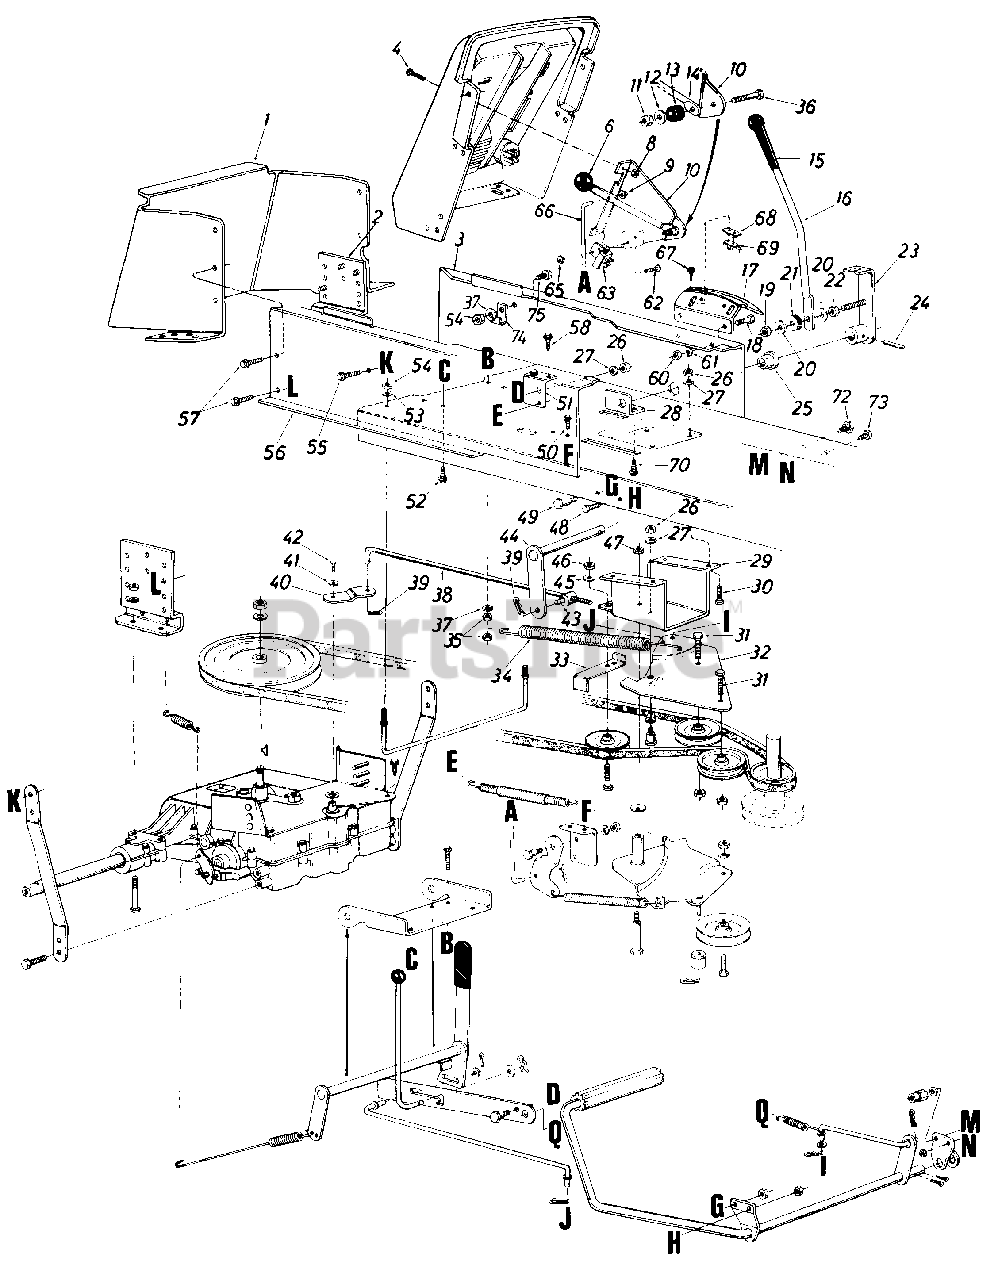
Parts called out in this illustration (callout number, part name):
3	Side Panel Upper Frame L.H.
4	Truss. Mach. Scr. 1/4-20 x .50" Lg.
6	Ball Knob
8	Hex Sems Nut 1/4-20 Thd
9	Push Cap 1/4" Rod
10	Deck Clutch Control Brkt.
11	Hex Cent. L-Nut 1/4-20 Thd.
12	Fl-Wash. .281" I.D. x .734" O.D. x .063 Thk.
13	Rubber Wash. .330" I.D. x .87" O.D. x .32 Thk.
14	Blade Clutch Lever
16	Shift Lever
19	Hex Cent. L-Nut 5/16-18 Thd.
20	Fl-Wash. .344" I.D. x .875" O.D. x .063 Thk.
21	Rubber Wash. .330" I.D. x .87" O.D. x .32 Thk.
22	Hex Nut 5/16-18 Thd.
23	Handle Mount Brkt. Ass'y.
24	Spring Pin Spiral 1/4" Dia. x 1.5" Lg.
25	Plastic Hex Bearing .625" I.D.
26	Hex Nut 5/16-18 Thd.
27	L-Wash. 5/16" I.D.
28	Speed Control Shaft Brkt.
29	Transaxle Clutch Support Brkt.
30	Hex Bolt 5/16-18 x 1.0" Lg.
31	Hex Bolt 3/8-24 x 1.5" Lg.
32	Idler Bracket Ass'y.
35	Hex Cent. L-Nut 1/4-20 Thd.
36	Hex Bolt 1/4-20 X 1.25" Lg.
37	L-Wash. 1/4" I.D.
38	Shift Link
39	Hairpin Cotter 3/8"
40	Shifter Bracket
41	Belleville Wash. .25" I.D. x.375" O.D.
42	Hex Bolt 1/4-28 x .62" Lg.
43	Pivot Bushing
44	Speed Control Shaft Ass'y.
45	Fl-Wash. .385" I.D. x .87" O.D. x .060 Thk.
46	Hex Cent. L-Nut 3/8-24 Thd.
47	Hex Cent. L-Nut 3/8-16 Thd.
48	Hex Bolt 3/8-16 x .62" Lg.
49	Shoulder Bolt .500" Dia. x .340" Lg. (3/8-16)
50	Hex Thd. Rolling Scr. 1/4-20 0 x.50" Lg.
51	Parking Brake Cam Mtg. Brkt.
52	Hex Thd. Rolling Scr. 1/4-20 0 x.50" Lg.
53	L-Wash. 1/4" I.D.
54	Hex Nut 1/4-20 Thd.
55	Hex Wash. Hd. TT-Tap Scr. 3/8-16 x .5" Lg.
56	Side Panel Upper Frame-R.H.
57	Hex Wash. Hd. Tap Scr. 5/16-18 x 5/8" Lg.
58	Hex Thd. Rolling Scr. 1/4-20 0 x.50" Lg.
60	Hex Nut 5/16-18 Thd.
61	L-Wash. 5/16" I.D.
62	Truss Mach. Scr. #10-24 x .50" Lg.
63	Safety Switch
65	Hex Nut #10-24 Thd.
66	Deck Control Rod
67	Hex Wash. Hd. Scr. #8 x .50" Lg.
68	Insulator Nut Plate
69	Spring Switch
70	Hex Wash. Hd. AB-Tap Scr. 5/16 x .75" Lg.
72	Shld. Bolt .498" Dia. x .34"
73	Hex Bolt 3/8-16 x .62" Lg.
75	Hex Bolt 1/4-20 x 5/8" Lg.
